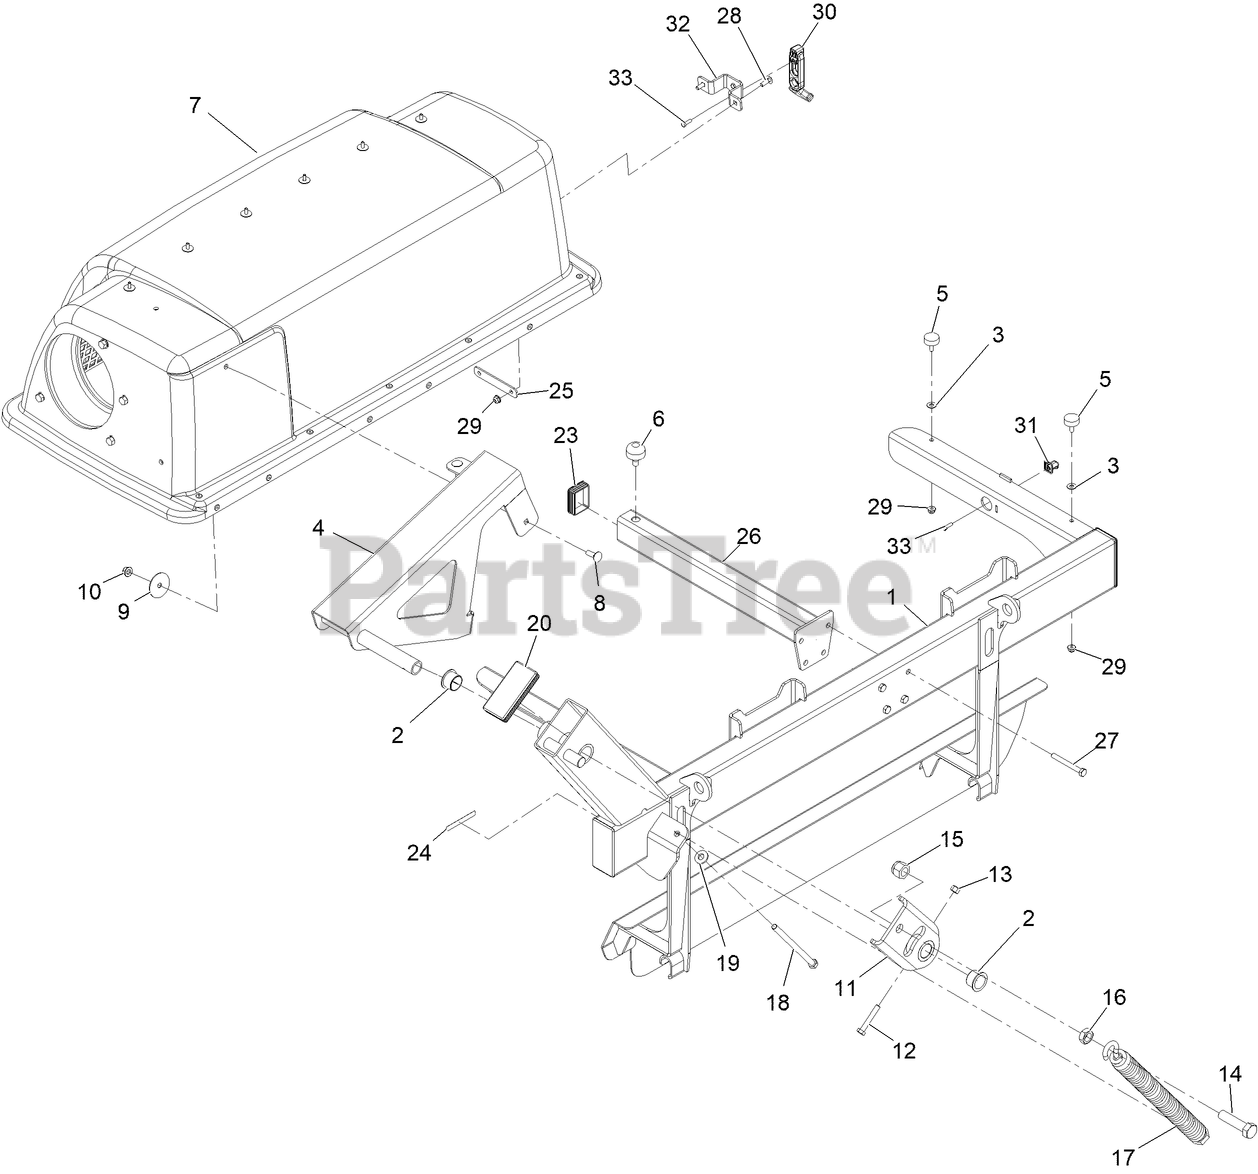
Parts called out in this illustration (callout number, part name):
1	FRAME-BAGGER
2	BUSHING
3	WASHER-FLAT
4	HOOD PIVOT ASM
5	BUMPER-RUBBER
6	BUMPER-RUBBER
7	ASM-Hood,Twin Bagger
8	BOLT-CARR
10	NUT-HF, NI
11	BELLCRANK ASM
12	SCREW-HH
13	NUT-LOCK, NI
14	Screw-HH
15	NUT-LOCK, NI
16	NUT-JAM
17	SPRING-EXTENSION
18	BOLT-TAP, HH
19	WASHER-BELLEVILLE
20	CAP-END
23	CAP-END
24	DECAL-WARNING
25	STRAP-BAGGER HOOD LATCH
26	ASM-Center Bagger Support [black]
27	SCREW-HH
28	SCREW-CARR
30	LATCH-RUBBER
31	LATCH-KEEPER
32	BRACKET-BAGGER HOOD LATCH
